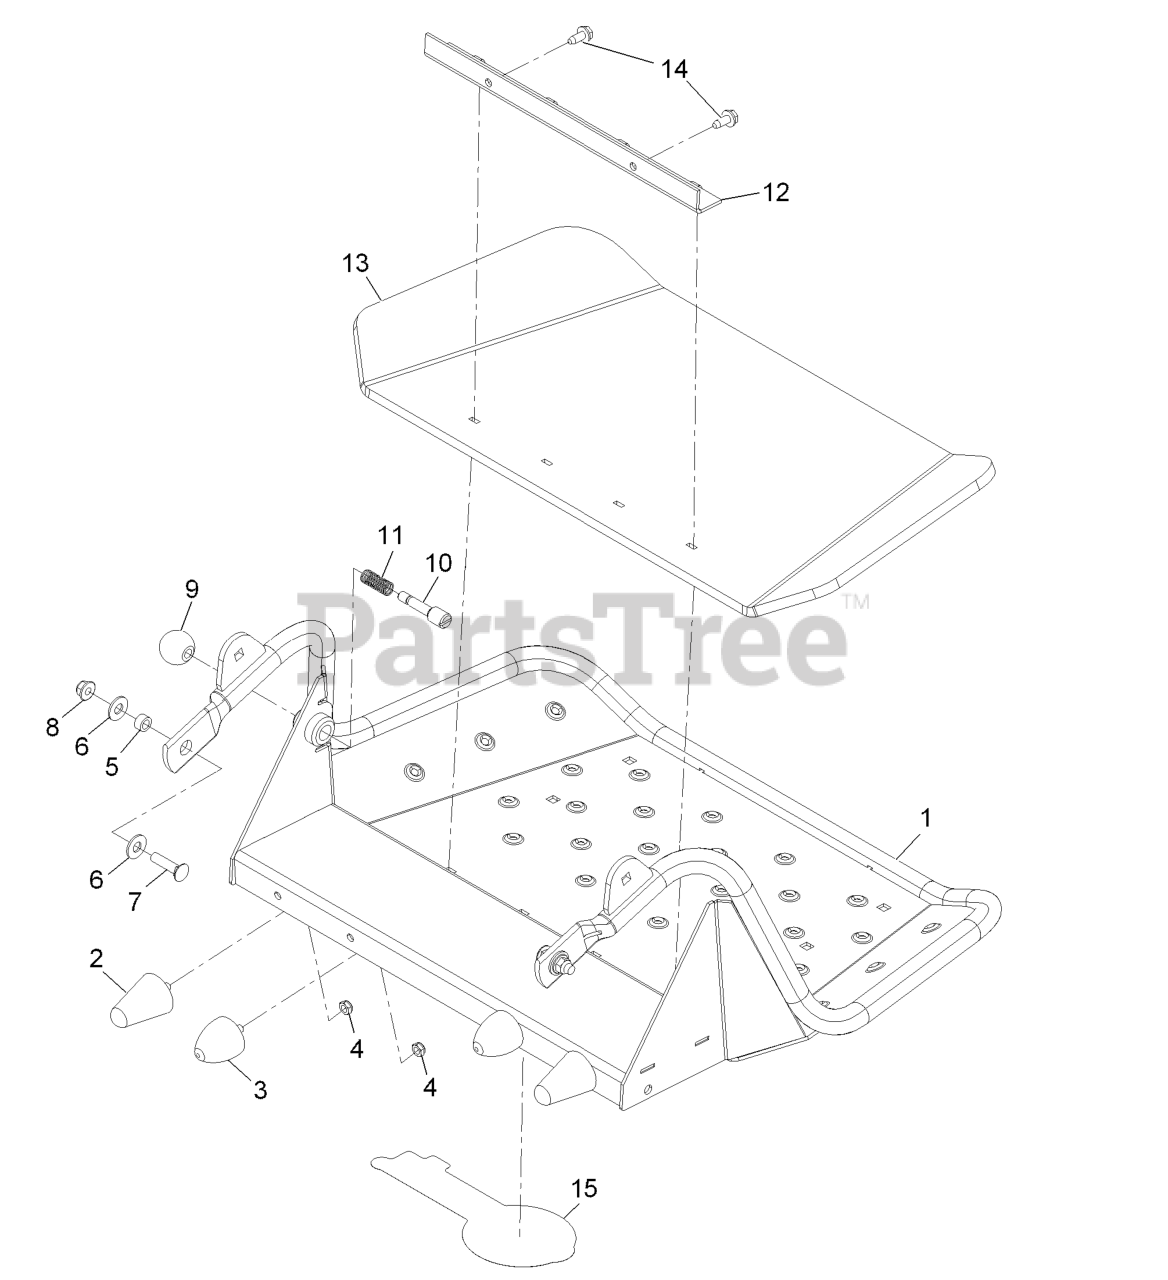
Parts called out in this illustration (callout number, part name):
1	PLATFORM ASM
2	BUMPER-RUBBER
3	BUMPER-RUBBER
4	NUT-LOCK, NI
5	SPACER
6	WASHER-FLAT
7	SCREW-CARR
8	NUT-HF, NI
9	KNOB-BALL
10	PIN-LATCH
12	CLAMP-SHIELD
14	Screw-HWH 5/16-18 X 3/4 Tf
15	DECAL, EXMARK LOGO
